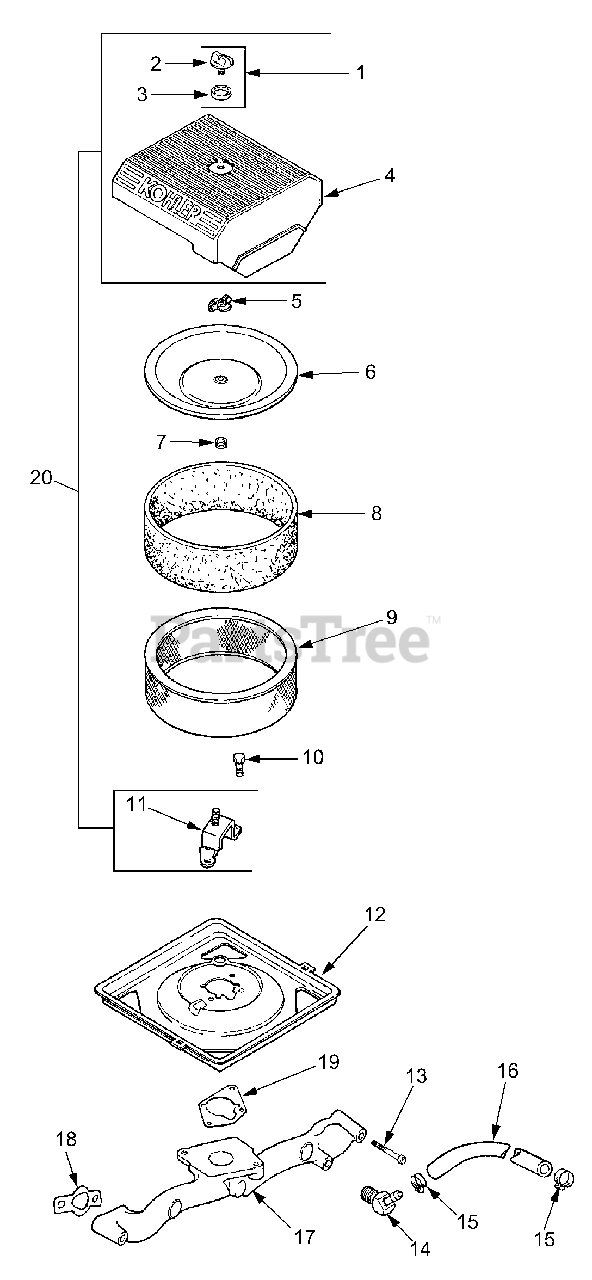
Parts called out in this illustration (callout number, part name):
1	Kit, Knob w/Seal
3	Seal, Air Cleaner Cover Knob
4	Cover, Air Cleaner
6	Cover, Inner Air Cleaner
7	Seal, Inner Air Cleaner
8	Precleaner, Element
9	Element, Air Cleaner
10	Screw, Hex Flange M6 x 1.0 x 16
11	Bracket, Air Cleaner Base
12	Base, Air Cleaner
13	Screw, Hex Flange M6 x 1.0 x 55
14	Connector, Hose 45°.
15	Clamp, Hose
16	Line, Fuel 17"
17	Manifold, Intake
18	Gasket, Intake Manifold
19	Gasket, Air Cleaner Base
20	Kit, Air Cleaner Cover
